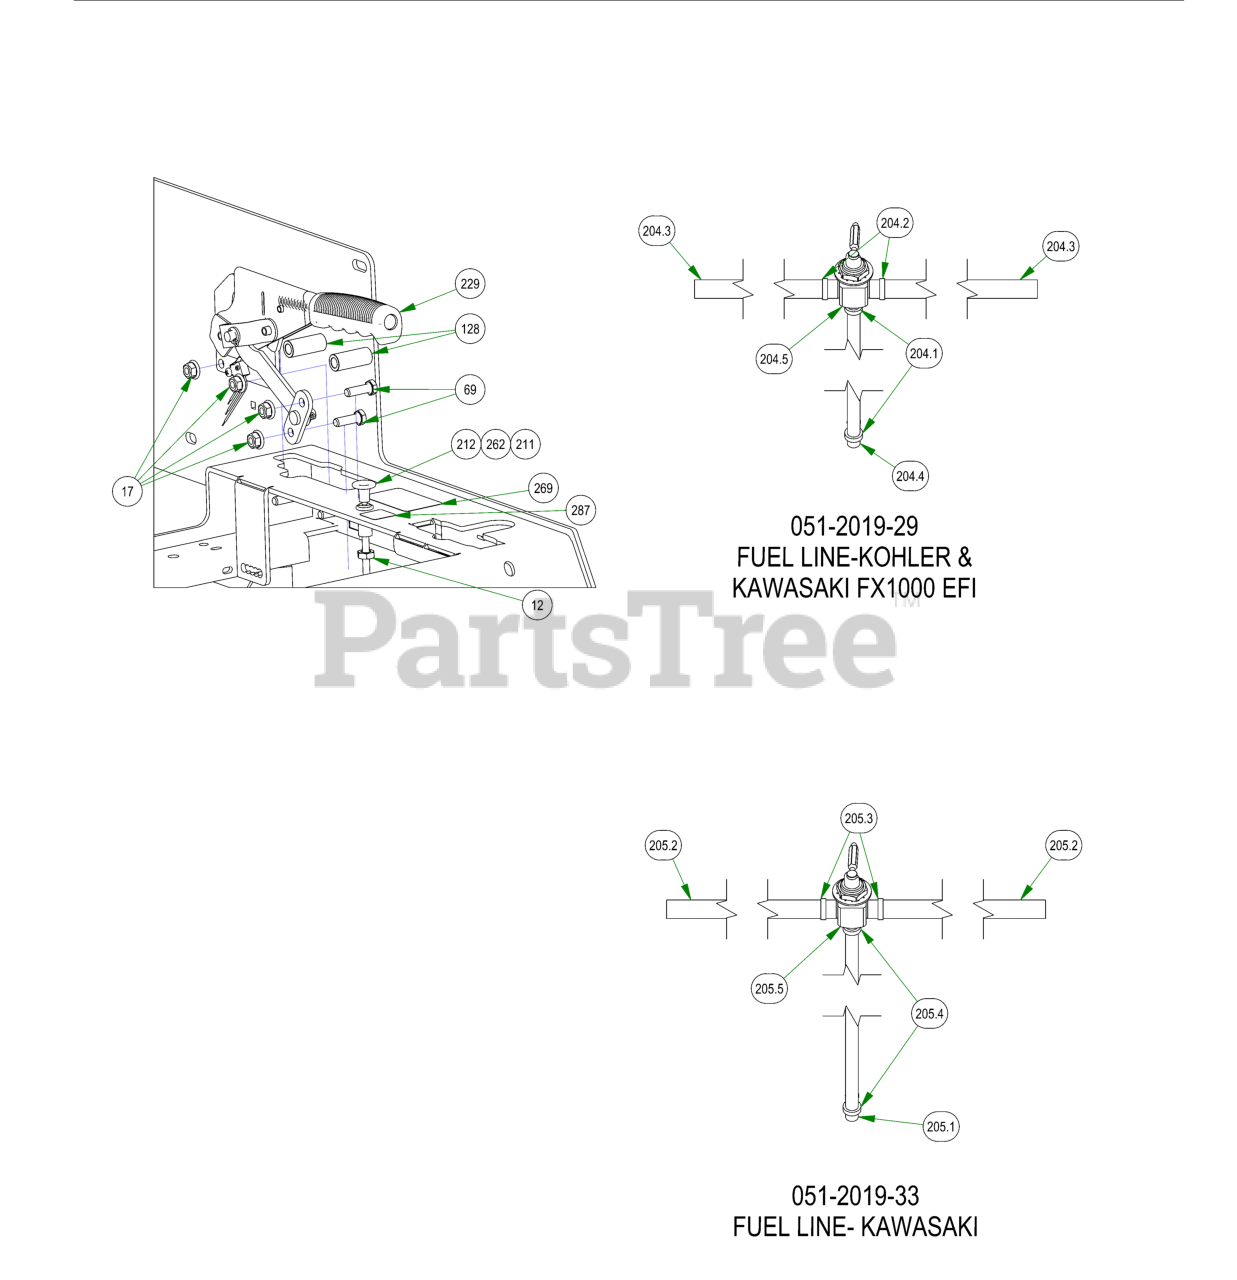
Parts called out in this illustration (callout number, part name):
12	3/8-24 HEX NUT ZINC YELLOW
17	5/16-18 NYLON INSERT FLANGE LOCKNUT ZINC
69	5/16-18 X 1 HEX CAP SCREW (GR.5) ZINC
128	.380 ID X .625 OD X 1.500 LGTH 2019 OUTLAW BRAKE HANDLE
204.1	1/4 Fuel Hose Clamp
204.2	5/16 Fuel Line Clamp
204.3	5/16" fuel line hose
204.4	1/4" Fuel Line Hose
204.5	3 Way Fuel Shut-Off Valve 5/16 x 5/16 x 1/4
205.1	1/4" Fuel Line Hose
205.2	5/16" fuel line hose
205.3	5/16 Fuel Line Clamp
205.4	1/4 Fuel Hose Clamp
205.5	3 Way Fuel Shut-Off Valve 5/16 x 5/16 x 1/4
211	Choke
212	Choke for 36Hp Vanguard & FX1000 Kawasaki
229	2019 Brake Handle Assembly
262	Code Indicator Light
269	2018 Out/XP/Diesel Brake Decal
287	2019 MIL Decal For Rogue EFI Models
